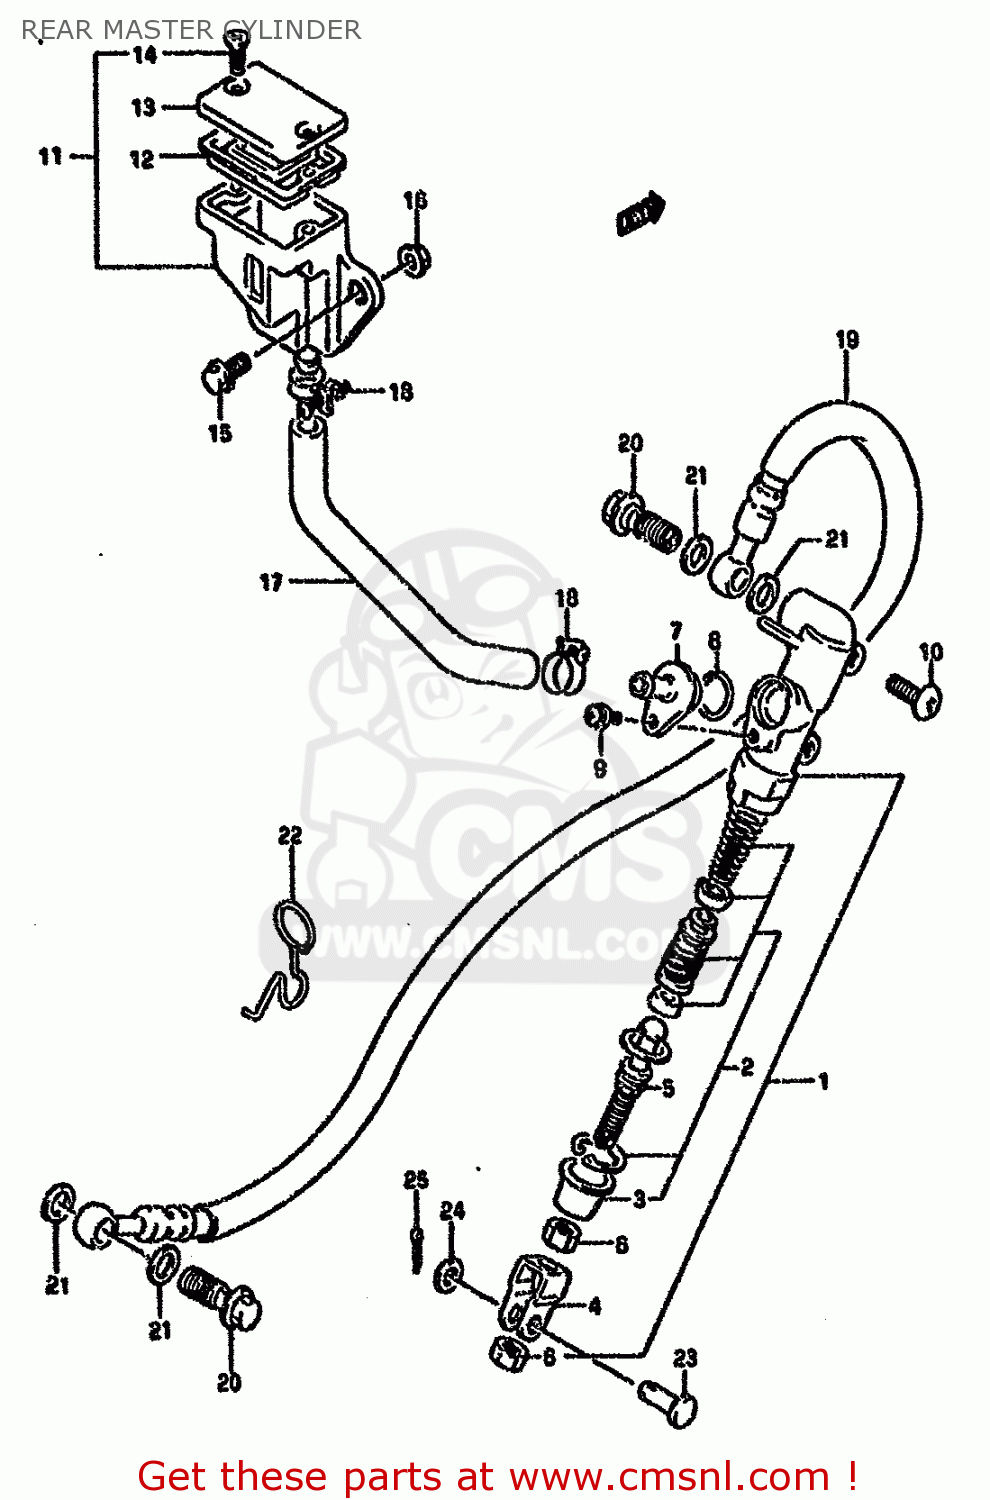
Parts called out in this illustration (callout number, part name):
1	CYLINDER ASSY,RR MASTER
2	PISTON/CUP SET
3	BOOT
4	YOKE
5	ROD,PUSH
6	NUT
7	CONNECTOR
8	O RING
9	SCREW
10	BOLT(6X21)
11	TANK ASSEMBLY,RESERVOIR
12	DIAPHRAGM
13	CAP
14	SCREW
15	BOLT
16	NUT
17	HOSE,RESERVOIR TANK
18	CLIP
19	HOSE,RR BRAKE
20	BOLT UNION
21	WASHER(10X15X1.5)
22	GUIDE,RR BRAKE HOSE
23	PIN
24	WASHER
25	PIN
